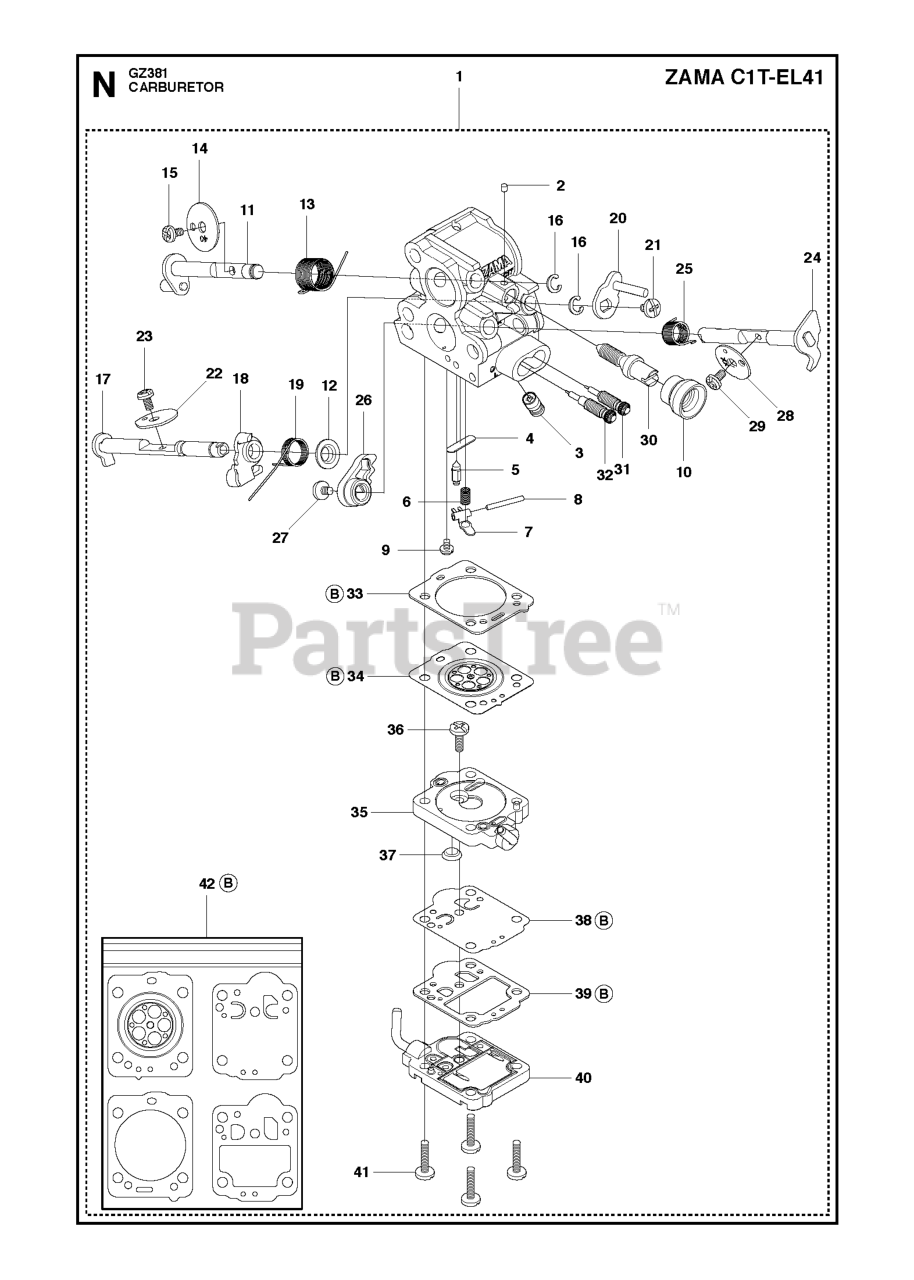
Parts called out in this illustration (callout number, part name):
1	CARBURETOR
3	NOZZLE ASSY
4	PLUG WRENCH
5	INLET NEEDLE
6	SPRING
8	PIN RETAINING SCREW
10	CAP ZAMA 0051034
11	SHAFT ASSY
12	COLLAR ZAMA 005020
17	SHAFT ASSY
24	SHAFT ASSY
30	IDLE SCREW
34	DIAPHRAGM
37	STRAINER
38	DIAPHRAGM
42	GASKET KIT
